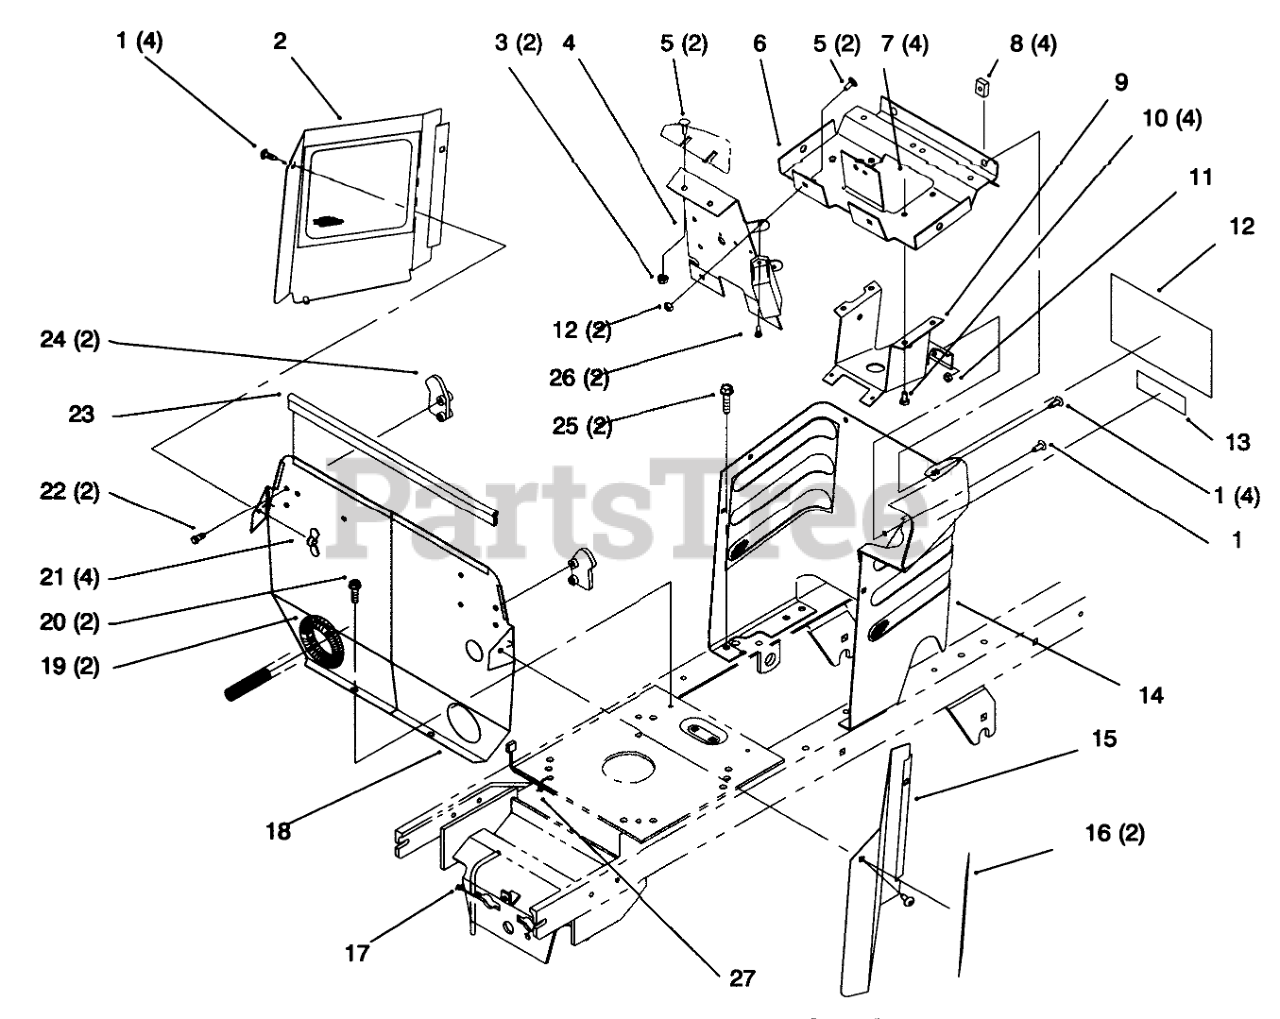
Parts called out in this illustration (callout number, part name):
1	SCREW-HH
2	RH SIDE COVER ASM
3	NUT-KEPS
4	SUPPORT - DASH (BLACK)
5	SCREW-CARR
6	SUPPORT-DASH
7	NUT-HEX
8	NUT RETAINER - J TYPE
9	BRACKET-COLUMN, LOWER
10	SCREW-HH
11	NUT-LOCK, NI
12	Decal-Slope/Park Brake (Only On: 72046)
12	Decal-Danger (Only On: 72064)
13	DECAL-INSTRUCTION
14	Hoodstand W/Decals (Only On: 72046)
14	Hoodstand W/Decals (Only On: 72064)
15	LH COVER ASM
16	DECAL - 265-H
17	TIE-CABLE
18	FIREWALL
19	COVER-SHAFT, DRIVE
20	SCREW-HWH
21	NUT-WING
22	SCREW-PLASTITE
23	TRIM-SEAL, FIREWALL
24	LATCH-HOOD
25	SCREW-HWHTF
26	SCREW-PPHTF
27	TIE-CABLE
